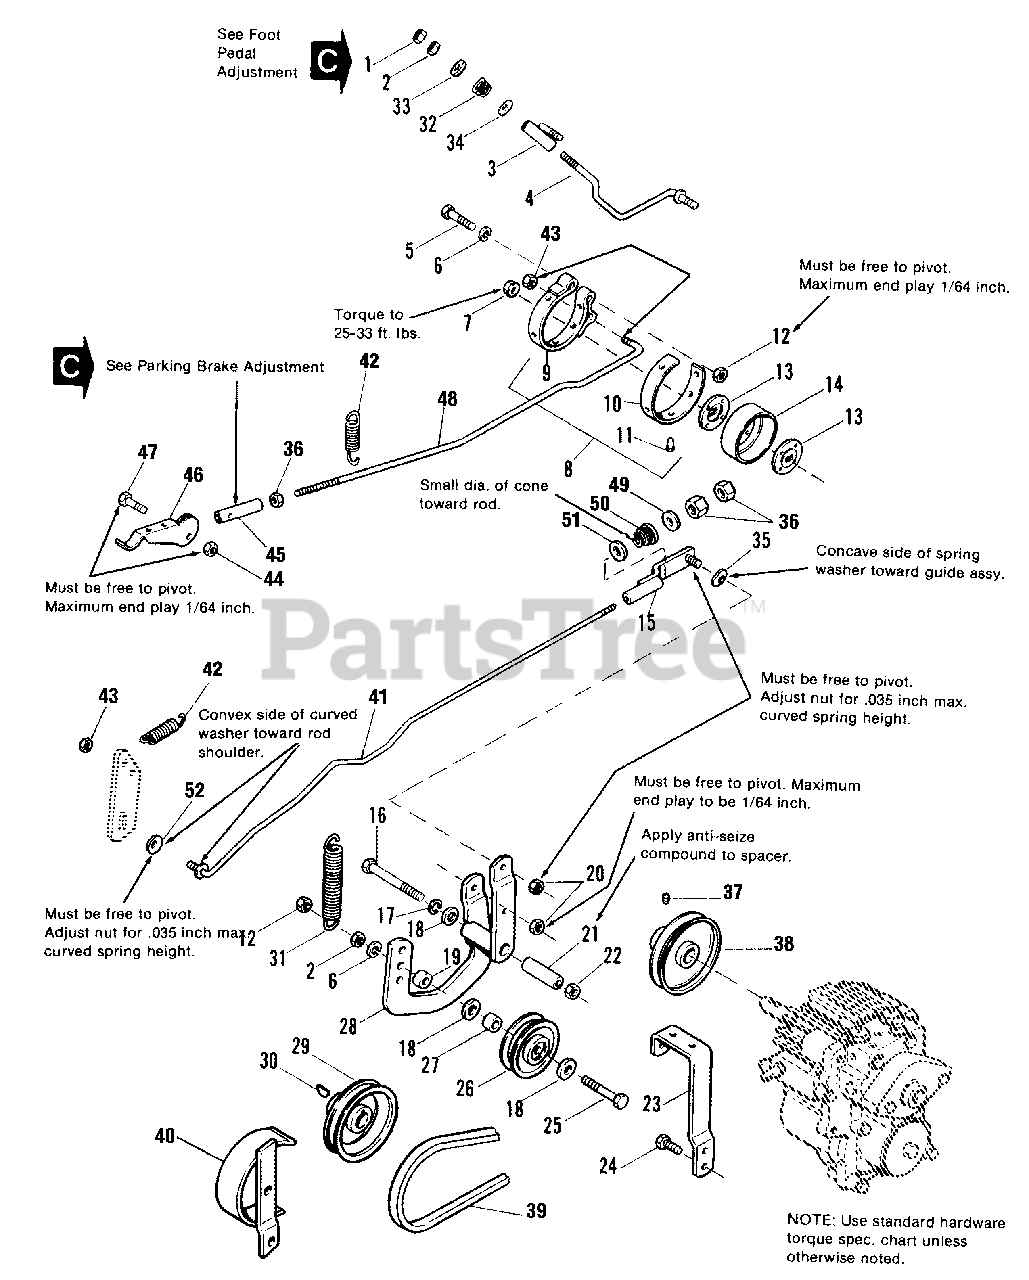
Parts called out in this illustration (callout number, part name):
1	LOCKNUT, Hex, Esna, 3/8-16
2	NUT, Hex, Full 3/8-16
3	GUIDE ASSY., Rod
5	CAPSCREW, Hex Hd., 3/8-16 x 1-3/4
6	LOCKWASHER, 3/8
7	LOCKNUT, Hex, Flange, 7/16-14
8	BAND ASSY., Brake
10	LINING, Brake
11	RIVET, 3/16 x 1/4
12	LOCKNUT, Hex, 3/8-16
13	WASHER, Special
14	DRUM, Brake
15	GUIDE ASSY., Rod
16	CAPSCREW, Hex Hd., 7/16-14 x 3-3/4
17	LOCKWASHER, 7/16
18	WASHER, Plain, 3/8
20	LOCKNUT, Hex, 5/16-18
22	NUT, Hex, Full, 7/16-14
24	SCREW, Self Tapping, 3/8 x 3/4
25	CAPSCREW, Hex Hd., 3/8-16 x 2-1/2
26	PULLEY ASSY.
28	LEVER ASSY., Idler
29	PULLEY
30	KEY
32	SPRING, Cone
35	WASHER, Curved, Spring
36	NUT, Hex, Full, 5/16-18
37	SETSCREW, 5/16-18 x 3/8
38	PULLEY, Drive
39	V-BELT, Drive
40	GUARD ASSY.
41	ROD, Clutch
43	LOCKNUT, Hex, 5/16-18
44	LOCKNUT, Hex, 1/4-20
46	LEVER, Parking Brake
47	CAPSCREW, Hex Hd., 1/4-20 x 1
49	WASHER, 5/16
50	SPRING, Cone
52	WASHER, Curved, Spring
